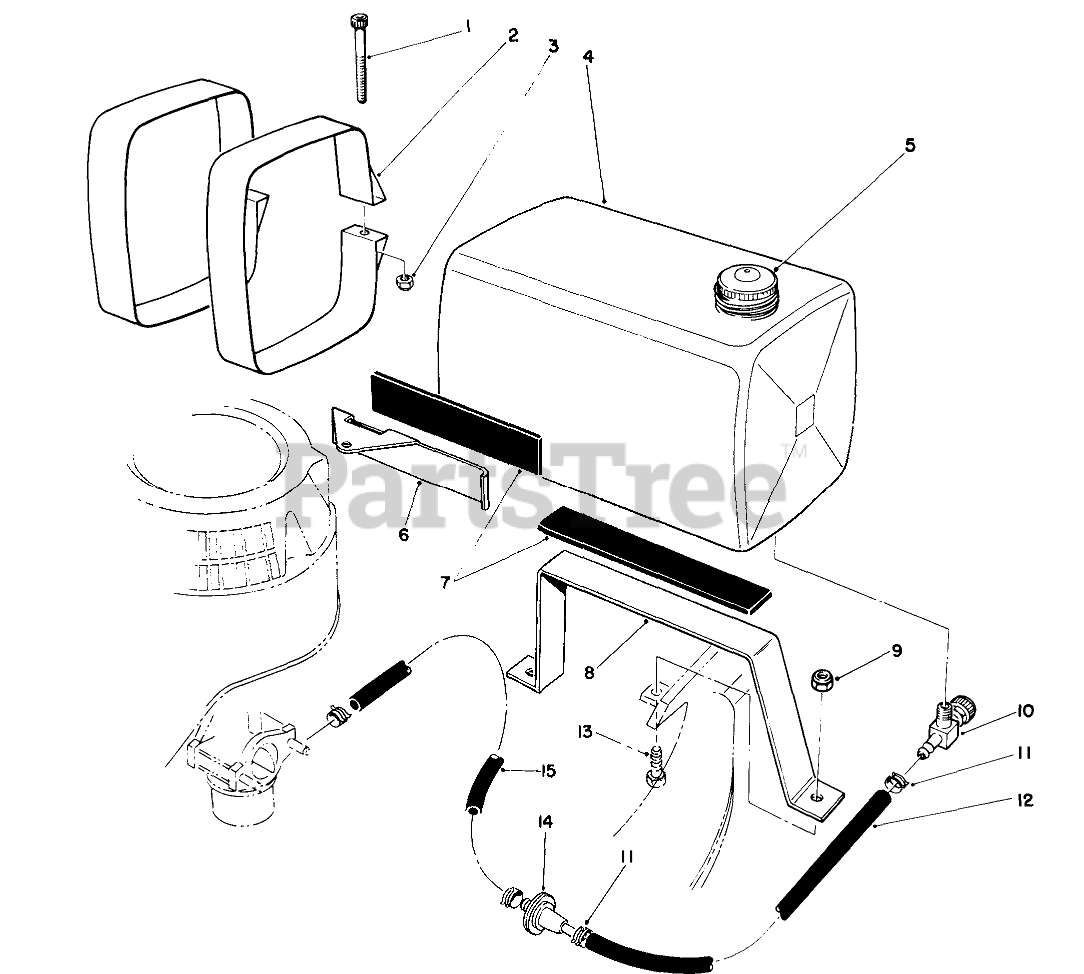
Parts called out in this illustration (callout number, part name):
1	SCREW-HSH
2	TANK STRAP WA
3	NUT-HEX
4	Tank-Gas (Incl. Ref. #5)
5	GAS CAP
6	FRT TANK MOUNT
7	ISOLATOR PAD
8	TANK BOTTOM MOUNT
9	NUT-LOCK, NI
10	.125 ID SHUTOFF VALVE
11	CLAMP-FUEL LINE
12	LINE-GAS
13	SCREW-HH
14	FILTER-FUEL
15	HOSE-FUEL
